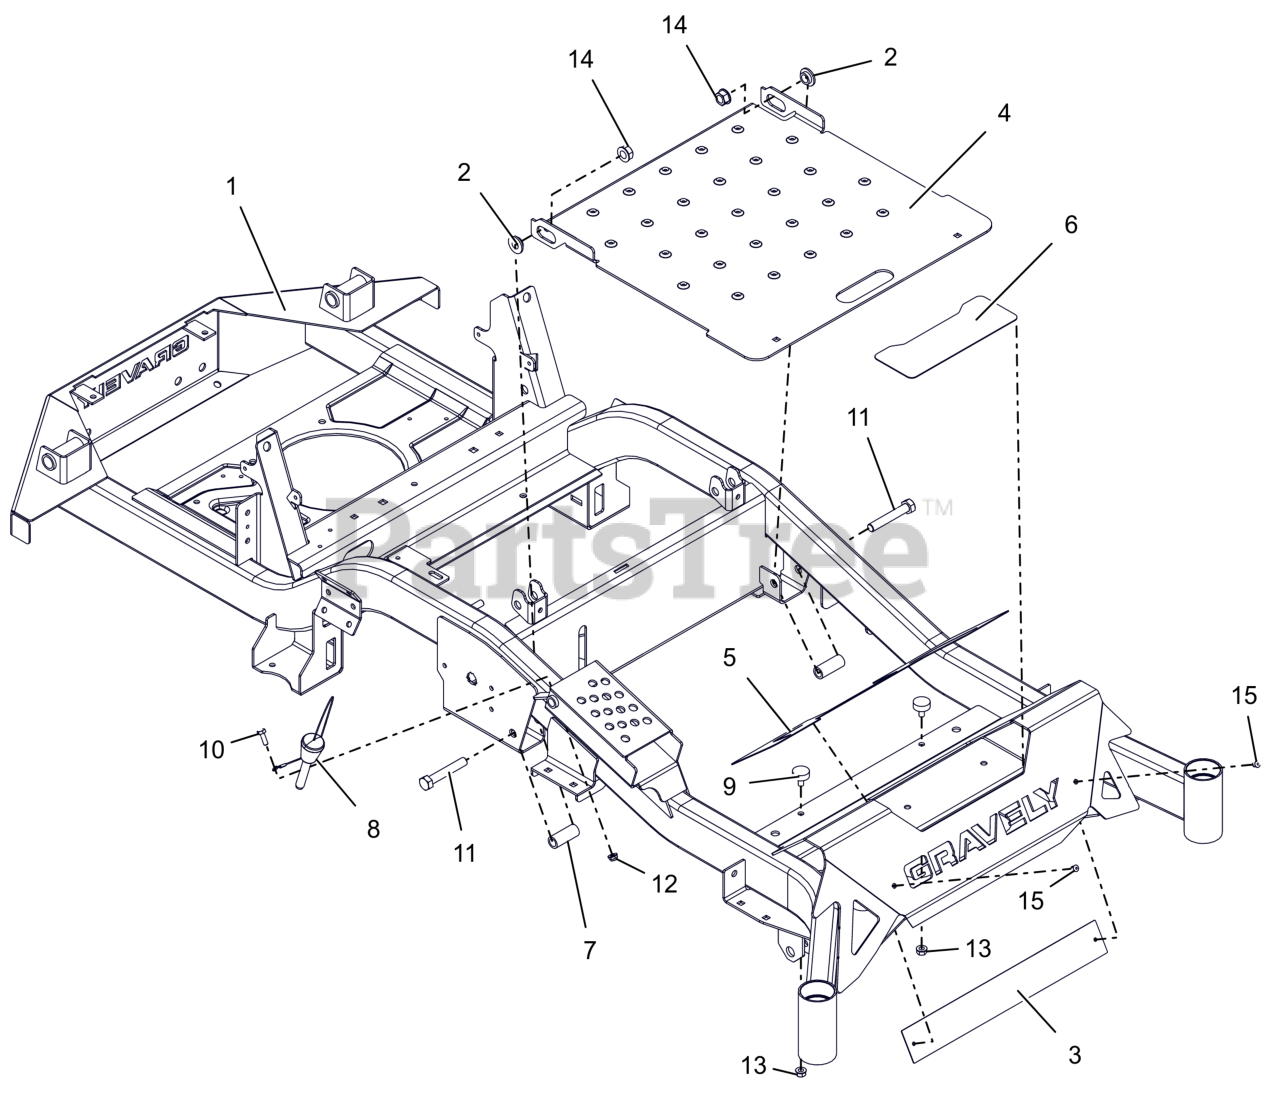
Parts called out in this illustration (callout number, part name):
1	HD 44-52 FRAME W/SAFETY DECALS
2	BSHG-FLG .515X.750X.310X1.120
3	PLATE, BACK FOOT-REST XL
4	KIT,ACCESS PANEL W/DECALS-RED
5	GRIP, FRONT
6	GRIP, STEP
7	SPACER, .515X.75X1.83
8	PIN, MAGNETIC .50X2.50
9	BUMPER, RUBBER
10	BLT, HEX .25-20X.75 G5 ZCC
11	BLT, HEX .50-13X3.00 G5 ZCC
12	NUT,NYL-FLG .25-20 GF ZCC
13	NUT,SPNLK-FLG .31-18 G5 ZCC
14	NUT-LK-TOP-FLG .500-13 GF ZCC
15	RIVET, .1875 AL/AL .126-.250
